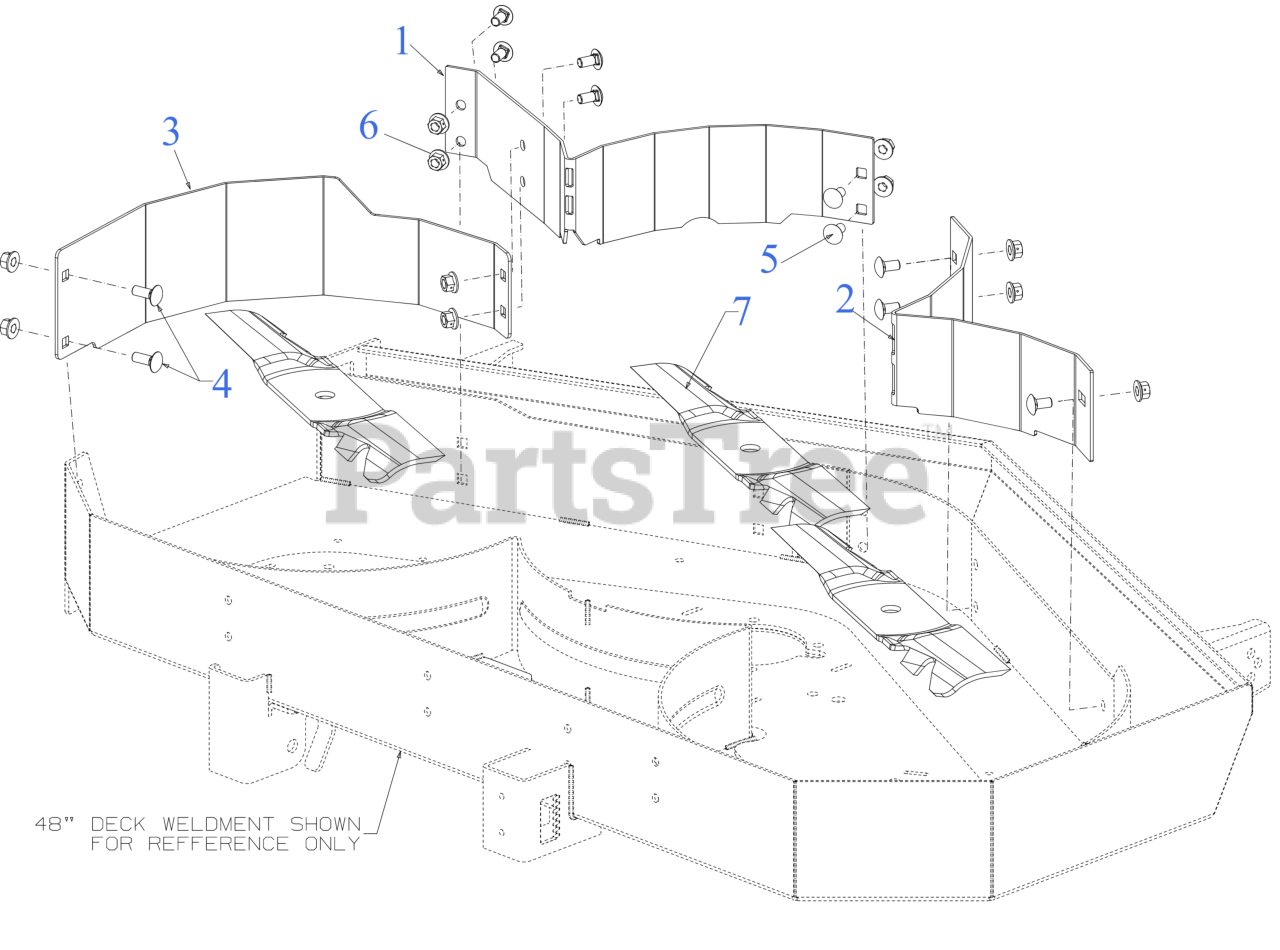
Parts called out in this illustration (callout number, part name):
2	MULCH BAFFLE (LEFT)
4	CARRIAGE BOLT 3/8-16 x 1.00 GR5
5	CARRIAGE BOLT 3/8-16 x .75
6	NUT-CTRLCK FLG HEX
7	17" XTREME BLADE
